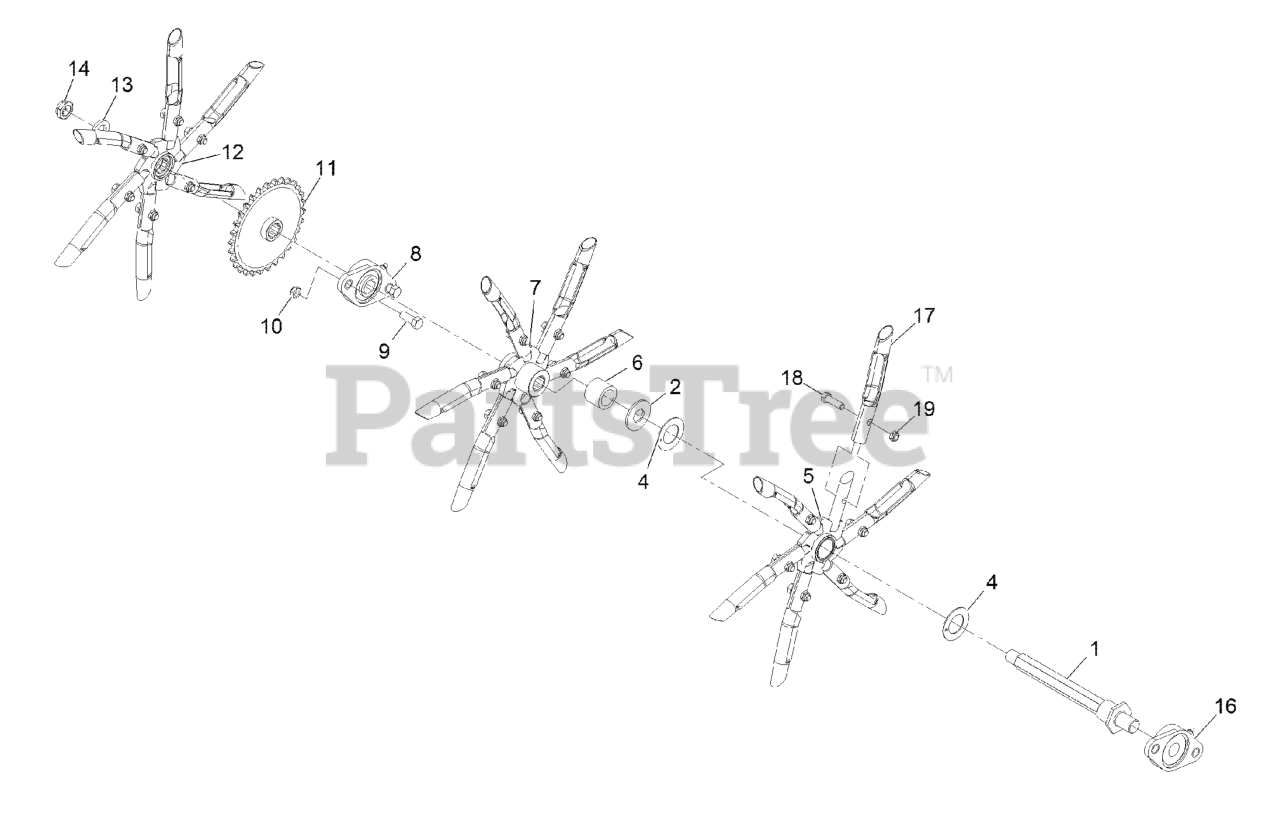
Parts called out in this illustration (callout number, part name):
1	TINE SHAFT ASM
2	KEEPER-TINE, FLOATING
4	WASHER-THRUST
5	FLOATING SPYDER ASM
6	SPACER-TINE
7	DRIVEN SPYDER ASM
8	BEARING-HEX BORE
9	SCREW-HH
10	NUT-LOCK
11	SPROCKET ASM
12	DRIVEN SPYDER ASM
13	WASHER-SPACER
14	NUT-LOCK
16	BEARING-ROUND BORE
17	TINE-CORING (3/4 INCH)
18	SCREW-HH
